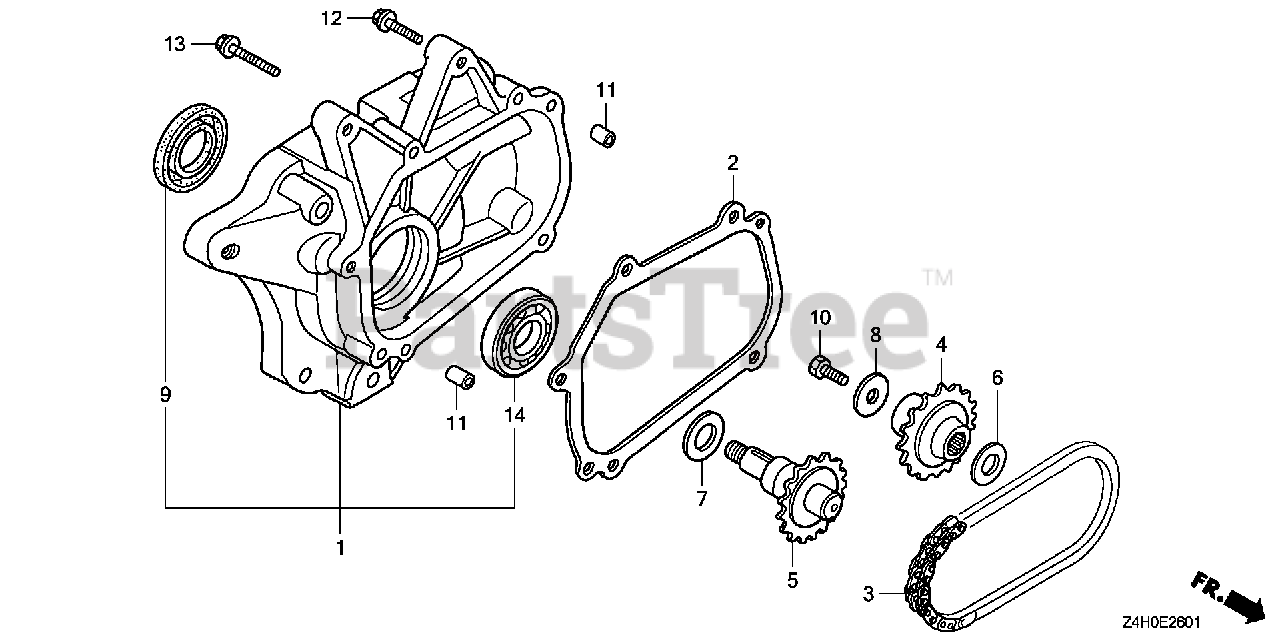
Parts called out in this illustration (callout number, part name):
1	COVER ASSY., CHAIN CASE
2	GASKET, CHAIN CASE COVER
3	CHAIN, P.T.O. DRIVE
4	SPROCKET, DRIVE (17T)
5	SHAFT, P.T.O. (16T)
6	WASHER, THRUST (20X1.00)
7	SPRING, THRUST
8	WASHER (8MM)
9	OIL SEAL (25X38X7)
9	OIL SEAL (25X38X7) (ARAI)
10	BOLT, HEX. (8X25)
11	PIN C, DOWEL (8X14)
12	BOLT, FLANGE (8X35)
13	BOLT, FLANGE (8X55)
14	BEARING, RADIAL BALL (6005)
